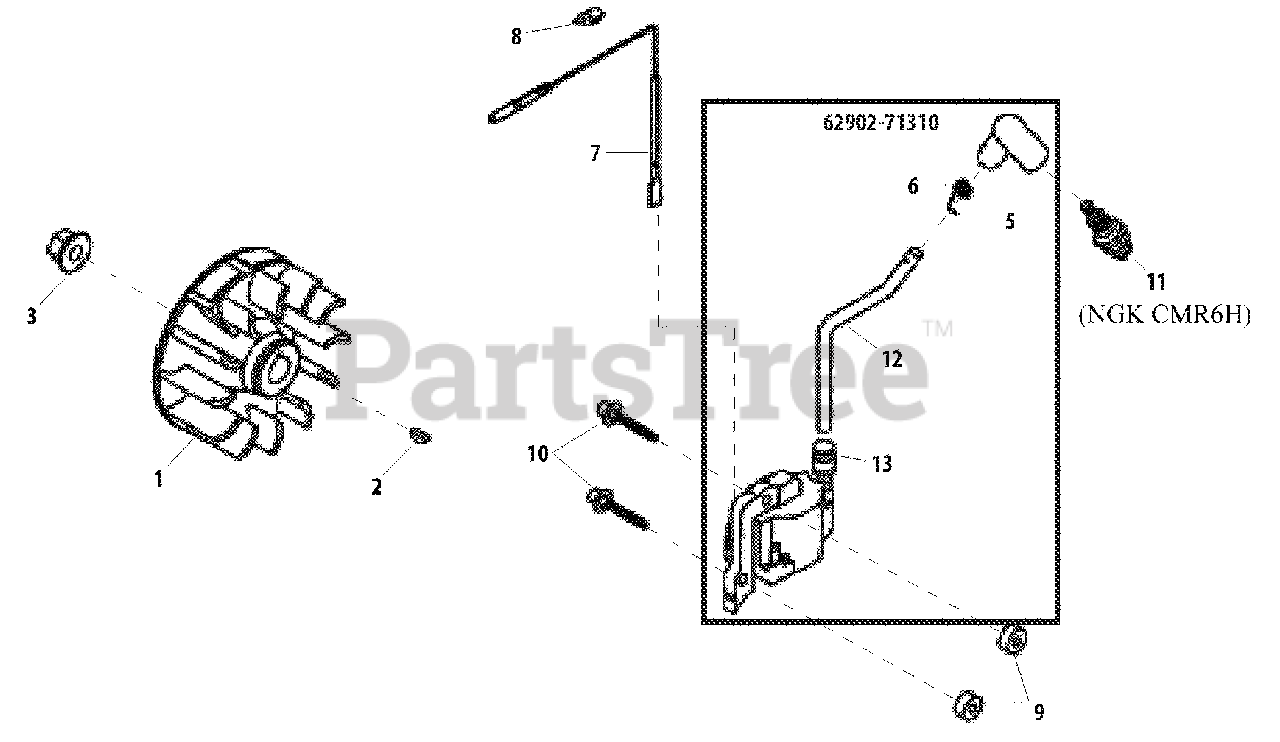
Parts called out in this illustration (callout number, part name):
1	FLYWHEEL
2	KEY, WOODRUFF 3×10
3	NUT M8
5	CAP, SPARK PLUG
6	TERMINAL, SPARK PLUG
7	LEAD
8	GROMMET, LEAD
9	INSULATOR 4.2×11×6
10	BOLT M4×26
11	SPARK PLUG
13	GROMMET
62902-71310	IGNITION COIL ASSY
